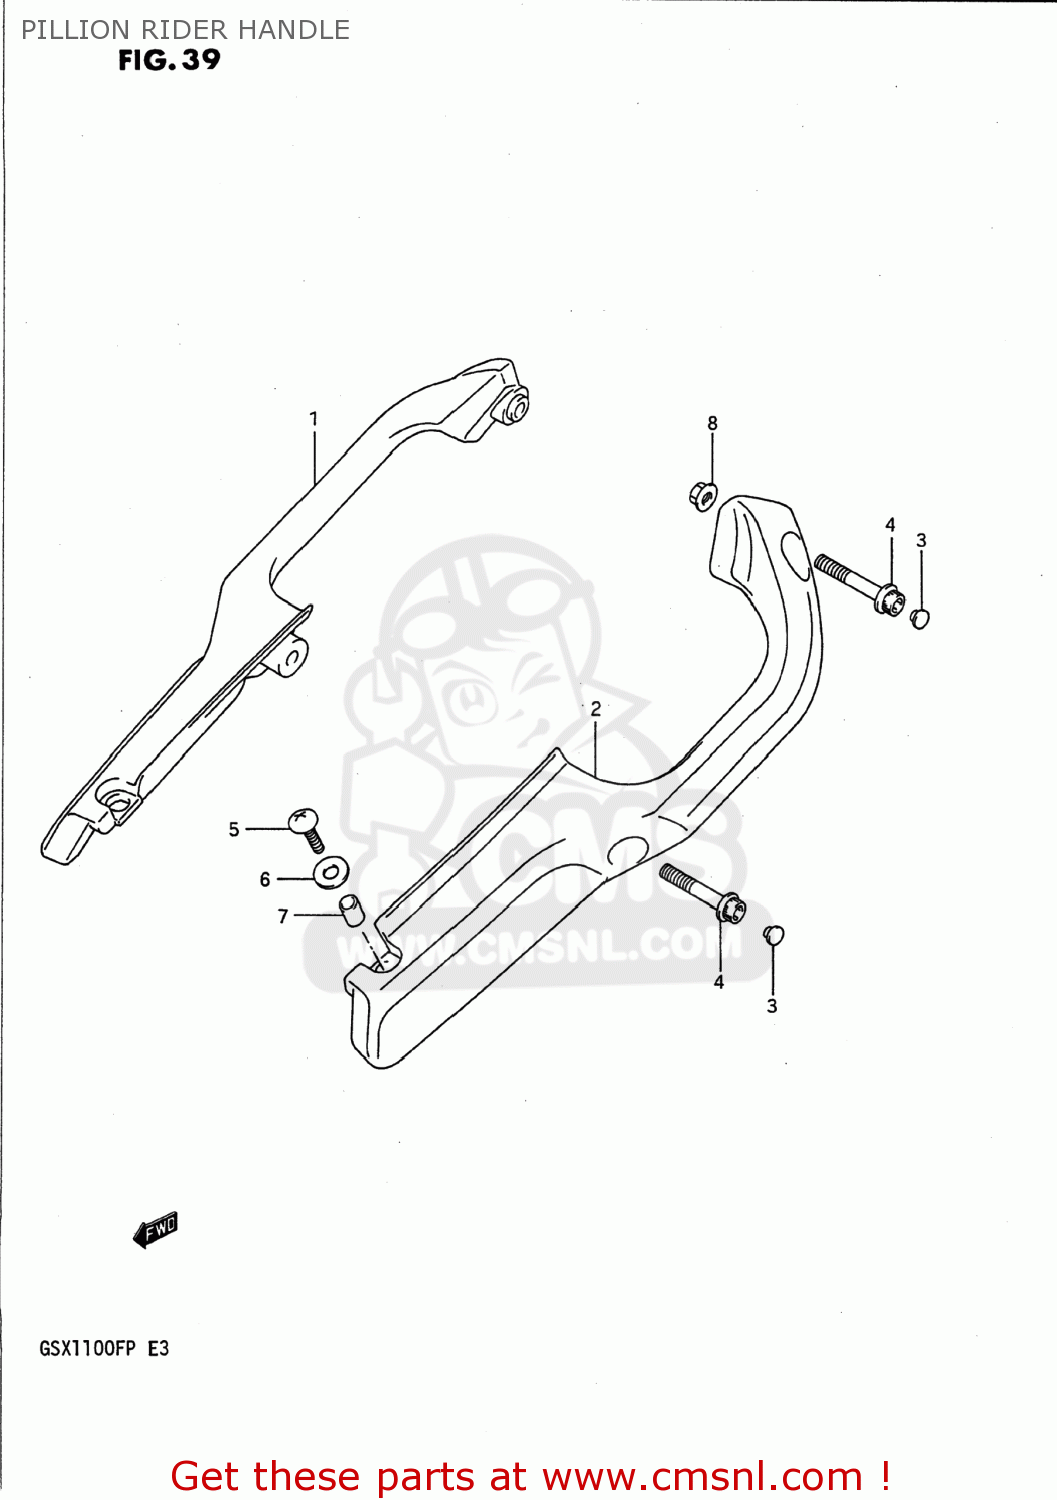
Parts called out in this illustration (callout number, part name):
1	HANDLE,PILLION RIDER,RIGHT
2	HANDLE,PILLION RIDER,LEFT
3	HANDLE,PILLION RIDER
4	BOLT 8X45
5	SCREW(6X20)
6	WASHER
7	SPACER (6X9X8)
8	NUT 8MM
